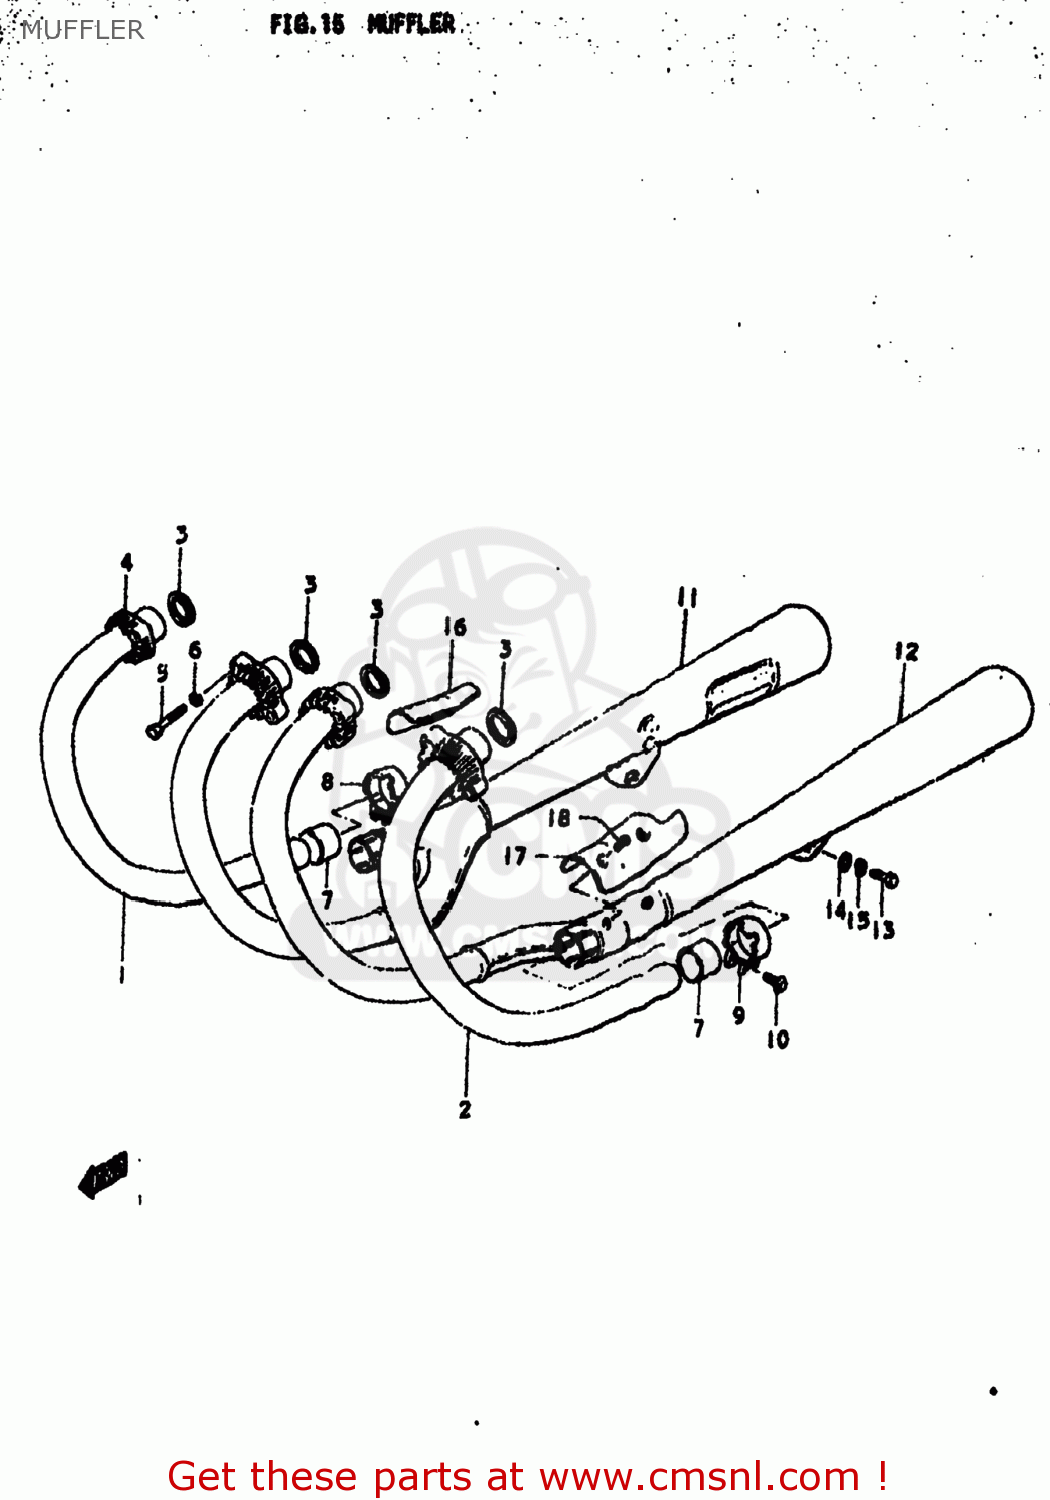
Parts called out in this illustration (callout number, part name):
1	PIPE,EXHAUST,RIGHT
2	PIPE,EXHAUST,LEFT
3	GASKET,EXHAUST PIPE (NAS)
4	CLAMP,EXHAUST PIPE
5	BOLT
6	LOCK WASHER
7	CONNECTOR,MUFFLER
8	CLAMP,MUFFLER CONNECTOR,R
9	CLAMP,MUFFLER CONNECTOR,L
10	BOLT
11	BODY,MUFFLER
12	BODY,MUFFLER
13	BOLT 10X30
14	WASHER
15	LOCK WASHER
16	COVER,MUFFLER,RIGHT
17	COVER,MUFFLER,LEFT
18	SCREW
